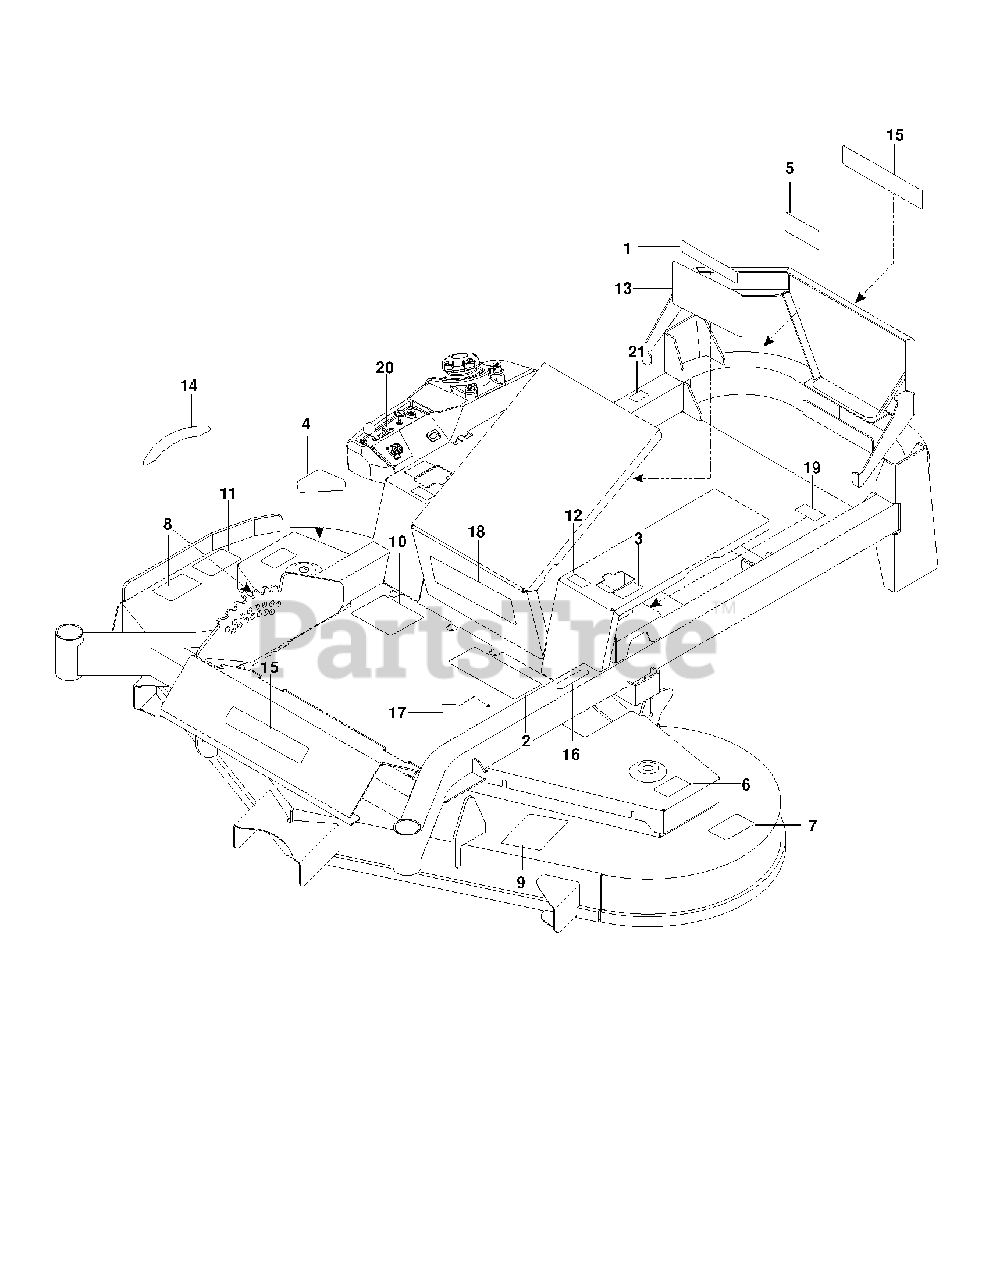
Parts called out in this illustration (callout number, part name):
2	DECAL, WARNING
3	DECAL, MOTION CONTROL
5	DECAL, BELT DRIVE
8	DECAL, EURO SEVERING
9	DECAL, BELT ROUTING
10	DECAL, WARNING
11	DECAL, CAUTION
12	DECAL, TRACKING
13	DECAL, SERVICE
14	DECAL, HEIGHT 5"
16	DECAL, PARK BRAKE
19	DECAL, FUEL
21	DECAL, ECM, AUSTRALIA
